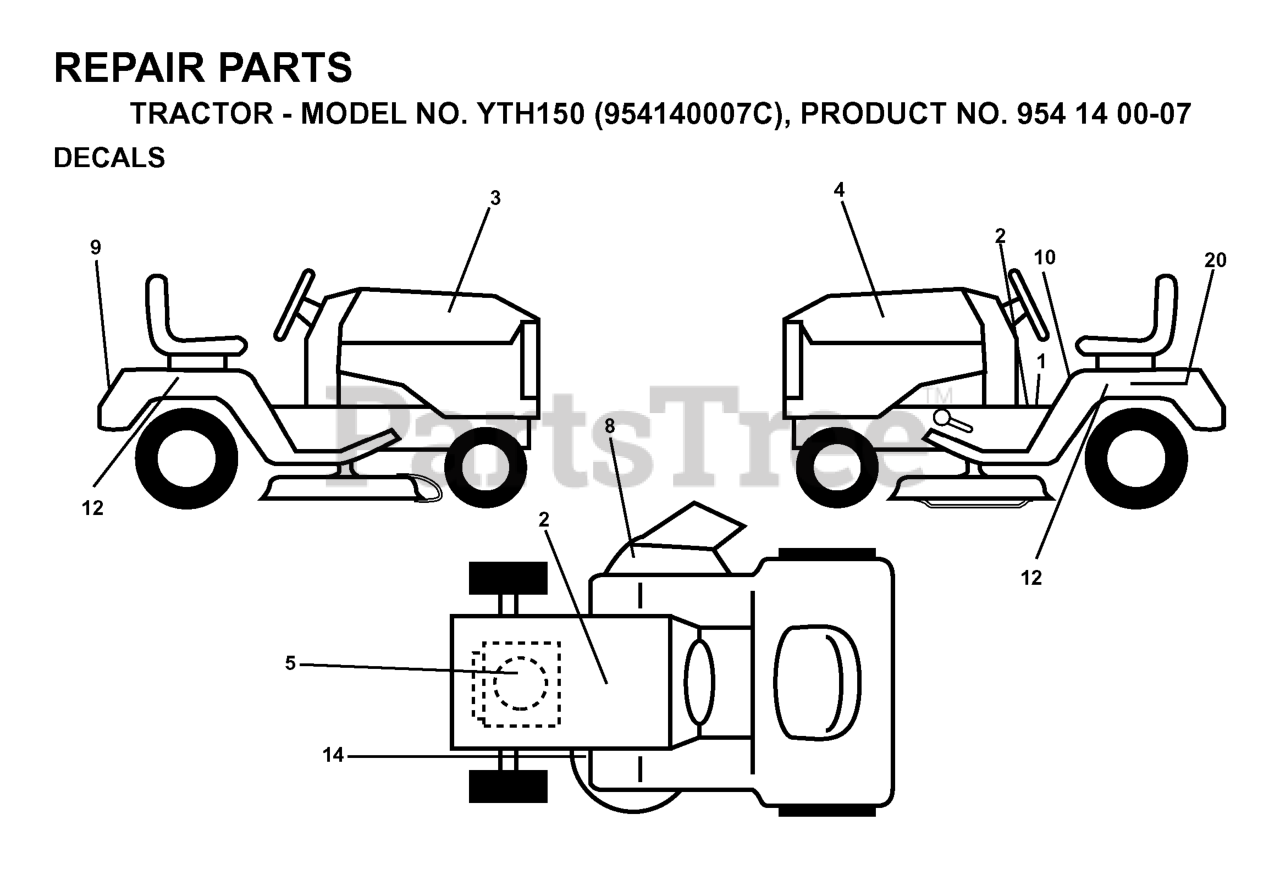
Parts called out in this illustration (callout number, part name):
2	DECAL BTRY SYMBOLS
3	DECAL, HOOD LH YTH150
4	DECAL, HOOD RH YTH150
8	DECAL WARNING (ENGLISH/FRENCH)
9	DECAL FENDER HUSQ
10	DECAL FENDER DANGER
14	DECAL V BELT SCHEMATIC
